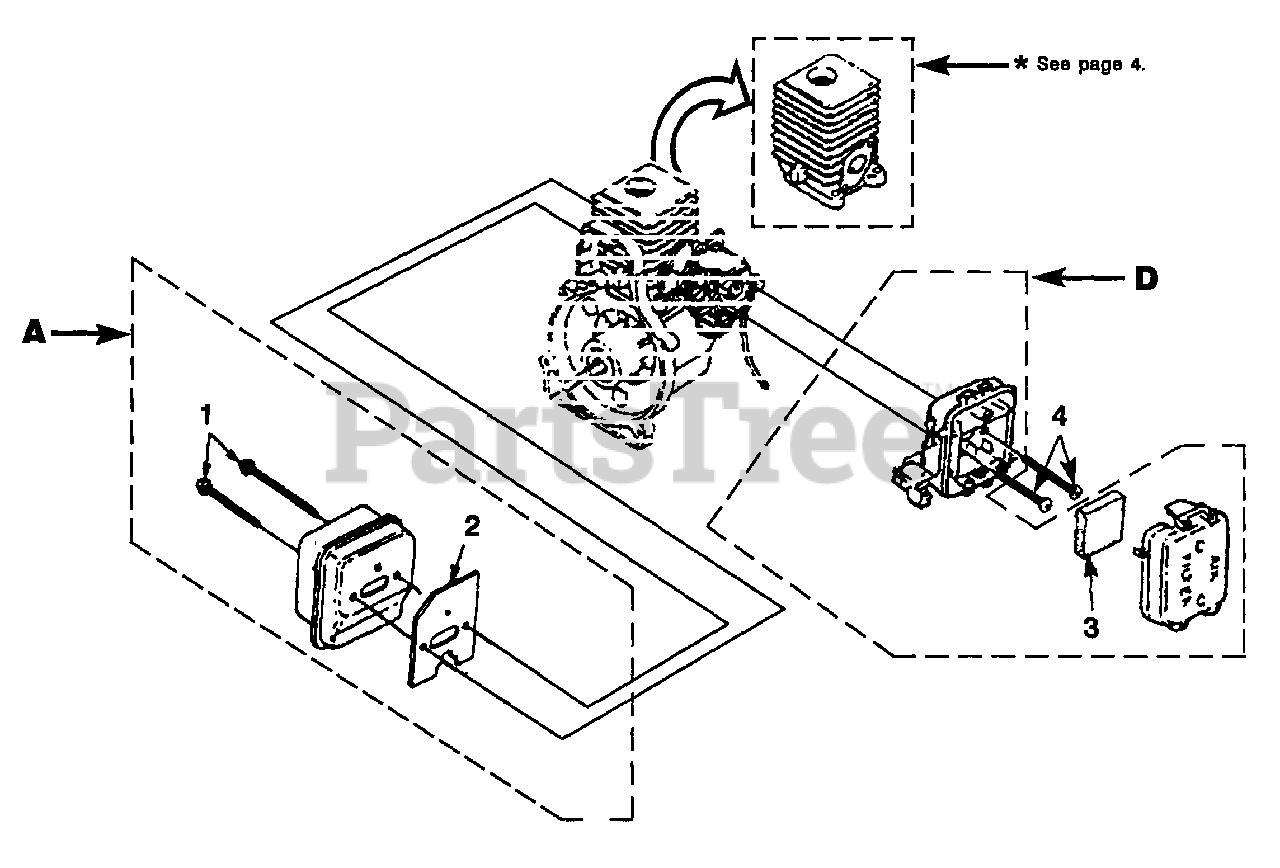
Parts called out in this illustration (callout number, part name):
1	SCREW-Sems Hex (10-24 X 2 1/2")
2	GASKET-Muffler
3	FILTER-AIR
4	SCREW-Sems Hsx Hd. (10-24 X 2 1/2")
A	MUFFLER COMPLETE (PLT3400 & PBC3600)
D	AIR FILTER KIT
